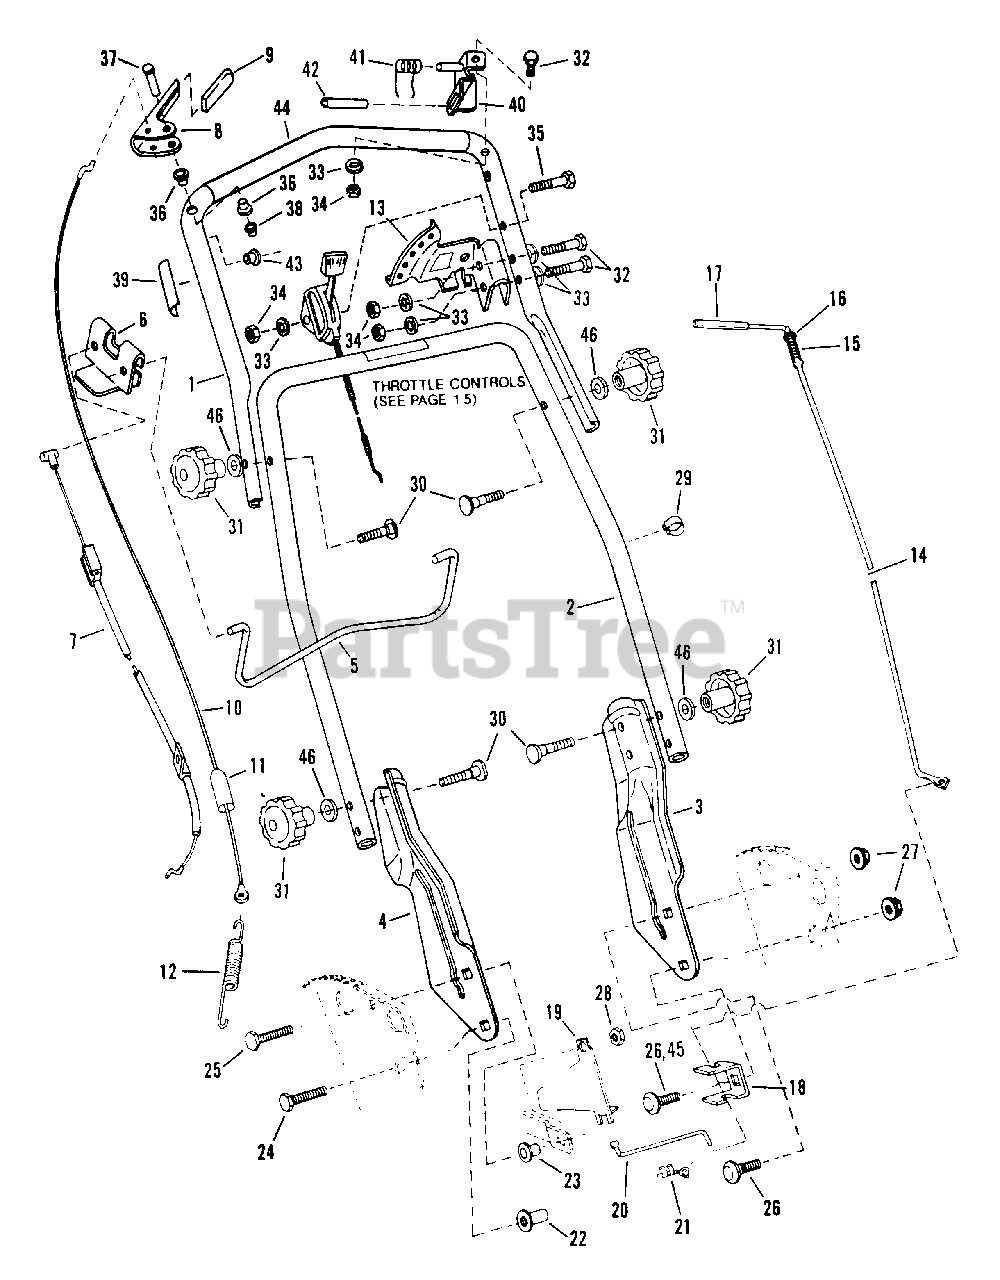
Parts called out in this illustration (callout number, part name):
1	HANDLE, Upper
2	HANDLE, Middle
3	HANDLE, Lower Left Hand
4	HANDLE, Lower Right Hand
5	CONTROL, Blade
6	CLIP, Blade Control
7	CABLE, Blade Control
8	HANDLE, Wheel Drive
9	GRIP, Wheel Drive Handle
10	CABLE, Clutch Pull (Z-BEND)
11	COVER, Vinyl
12	SPRING, Clutch
13	SECTOR, Speed
14	LEVER, Speed Control
15	SPRING, Speed Control
16	WASHER, 3/8" Flat
17	GRIP, Speed Control Handle
18	ANCHOR, Speed Control
19	GUIDE, Lower V-Belt
20	ROD, Transfer
21	CLIP, Transfer Rod
22	TEE-NUT, 5/16-18
23	BUSHING, Differential
24	BOLT, 5/16-18 x 3/4 Flange Lock
25	CAPSCREW, 5/16-24 x 1
26	BOLT, 5/16-18 x 5/8 Carriage
27	NUT, 5/16-18 Hex Flange Lock
28	NUT, 5/16-24 Center Lock
29	CLIP, Cable/Wiring
30	SCREW, 5/16-18 x 1-7/8 Curved Head
31	KNOB, 5/16-18
32	CAPSCREW, 1/4-28 x 1-3/8
33	LOCKWASHER, 1/4 Internal Tooth
34	NUT, 1/4-20 Hex
35	CAPSCREW, 1/4-28 x 1-3/4
36	BUSHING
37	PIN, Clutch Handle
38	PUSH-NUT
39	DECAL, Blade Control (R.H. Side)
39	DECAL, Wheel Control (Euro) (R.H. Side)
40	ASSEMBLY, Blade Control Bracket
41	SPRING, Blade Control
42	GRIP, Pivot
43	BUSHING
44	GRIP, Foam
45	DECAL, Speed Sector
46	LOCKWASHER, 5/16 Internal Tooth
